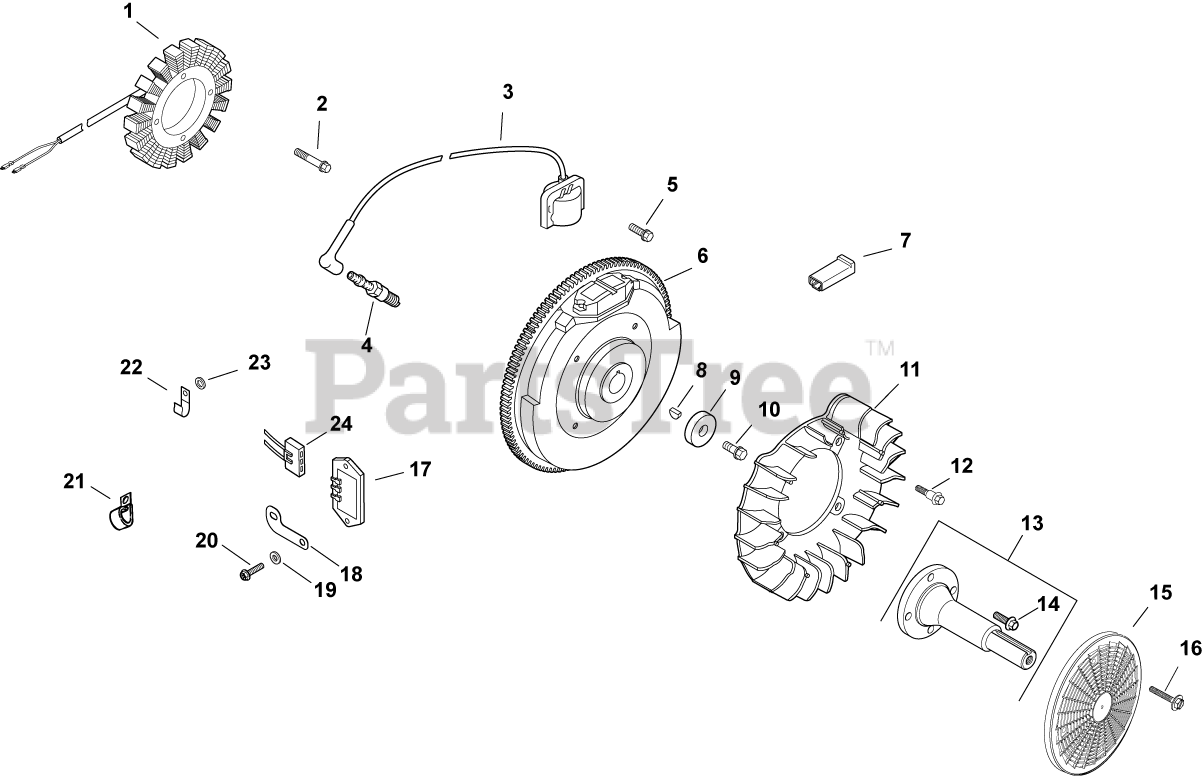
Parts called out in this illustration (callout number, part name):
1	KIT, 25 AMP STATOR ASSY.
2	SCREW, THD FROM M5X0.8X30
3	KIT, MODULE IGNTN (CDI FIXED)
4	PLUG, SPARK (PRO SERIES)
5	SCREW, FLG THD FRM M5X.8X20-(#25086399S)
7	CONNECTOR (1 CONTACT)
8	KEY, 3/16" X 5/8"
9	WASHER, FLAT 13/32"
10	SCREW, FLG M10X1.5X45 - (#25086361S)
11	FAN USE 24 157 11-S
12	BOLT, SHOULDER
13	SHAFT, FRONT DRIVE
14	SCREW, FLG M8X1.25X25
15	SCREEN, GRASS-USE 24 162 45-S
16	SCREW, FLG SEMS M4X.7X25
17	REG/RECTIFIER (20/25 AMP)-USE 25 403 20-
18	BRACKET, GROUND STRAP USE 24 518 12-S
19	WASHER, FLAT 3/16"
20	SCREW, PHL HD #11-16X7/8"
21	CLIP, TUBE & WIRING (KM)
22	CLIP, CABLE
23	WASHER, FLAT 7/32"
24	CONNECTOR
